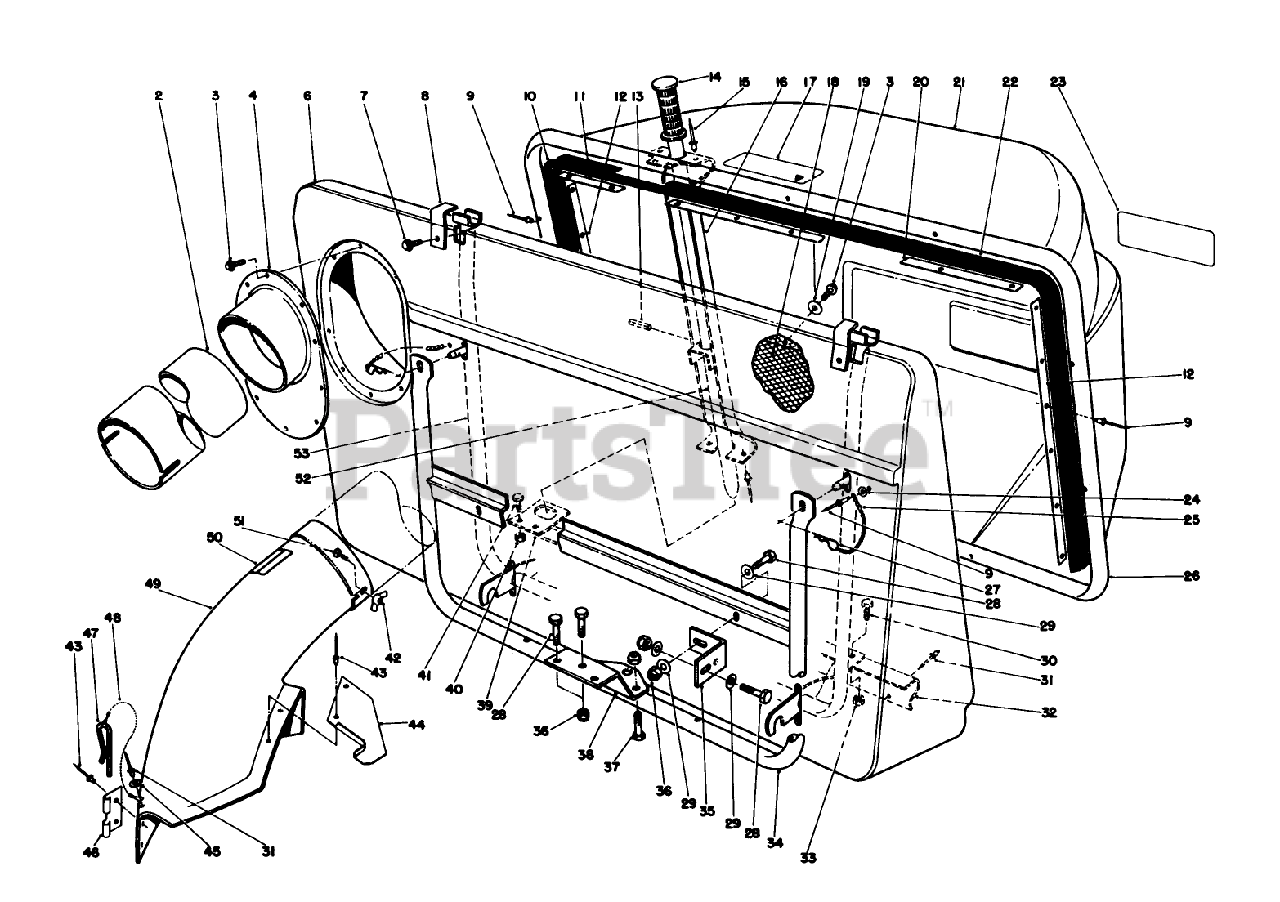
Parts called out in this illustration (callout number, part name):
3	SCREW-HWHTF
4	DUCT ADAPTER
7	SCREW-HWH
10	RH BAG SEAL
13	PIN-ROLL
15	RIVET-POP
19	WASHER-FLAT
24	WASHER
27	PIN-HAIR
28	SCREW-HH
29	WASHER-PLAIN
30	SCREW-HH
31	RIVET-BLIND
33	NUT-LOCK, CONE
34	BAG SUPPORT WA *
36	NUT-LOCK, NI
37	SCREW-HH
38	MTG PLATE *B
40	NUT-LOCK, CONE
41	SCREW-HH
42	NUT-WING SPECL
43	RIVET-BLIND
44	CHUTE SUPT BRKT
45	WASHER-PLAIN
46	BRACKET-MOUNTING, CHUTE
47	PIN-LOCKING, CHUTE
48	LANYARD
49	CHUTE ASM
51	BOLT-CARR
52	DUMP HANDLE ASM
